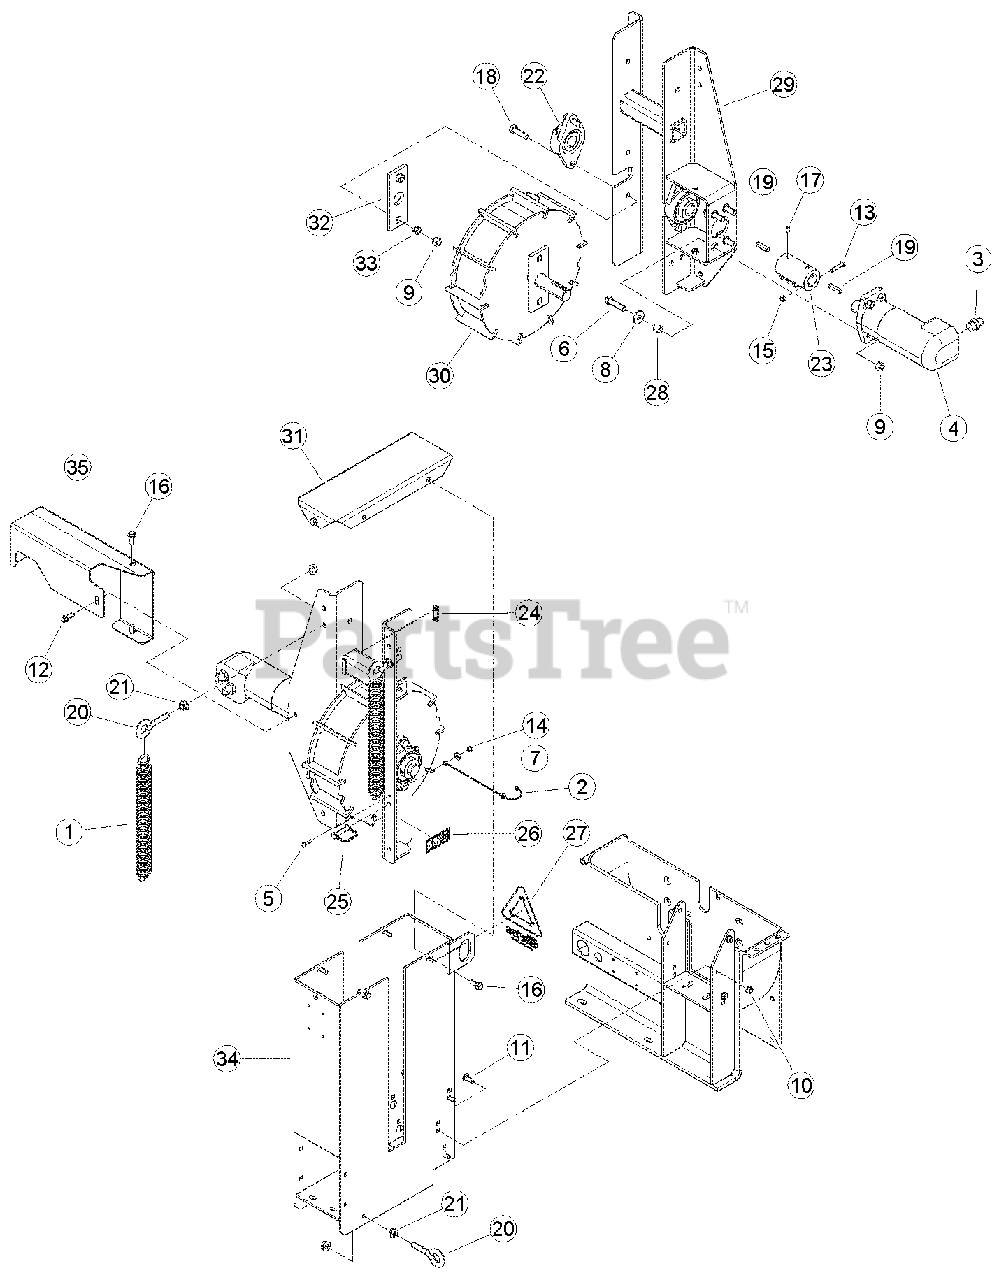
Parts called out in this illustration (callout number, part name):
1	SPRING, EXTENSION
2	LANYARD, NYLON
3	ADAPTER, -10 MORING / -8 MJIC
4	MOTOR, 19 CU IN HYDRAULIC
5	BOLT, 1/4 X 1 HEX HD GR5 ZP
6	BOLT, 1/2 X 2 HEX HD GR5 ZP
7	WASHER, 1/4 FLAT ZP
8	WASHER, 1/2 FLAT ZP
9	NUT, 1/2 CENTERLOCK GRB ZP
10	NUT, 3/8 SERR FLANGE NC ZP
11	BOLT, 3/8 X 1 CRG GR5 NC ZP
12	SCREW, 3/8-16 X 1 LG THD CUTT ZP
13	BOLT, 5/16 X 1-1/2 HEX HD GR5 ZP
14	NUT, 1/4 NE NYLOCK ZP
15	NUT, 5/16 NE NYLOCK ZP
16	BOLT, 3/8 X 1 SERR FLANGE GR5 NC ZP
17	SET SCREW, 3/8 X 1/2 CUP PT SKT
18	BOLT, 1/2 X 1-3/4 HEX HD GR5 NC ZP
19	KEY, 5/16 SQUARE X 1-1/2 LONG
20	EYEBOLT, 1/2 X 2 ZP
21	NUT, 1/2 SERR FLANGE NC ZP
22	BEARING, 1-1/4" DIA 2 BOLT FLANGE
23	COUPLER, 1-1/4" SHAFT
24	WEAR PAD, STD.SPRING HD FRONT
25	PIN, SNAP 3/8 X 1-1/2 USABLE LGH
26	DECAL, CRUSHING ISO
27	DECAL, CHIP IT
28	SPACER,0.75 X 0.620
29	WELDMENT, ROLLER SLIDE
30	WELDMENT, TOP GRAB ROLLER
31	WELDMENT, TOP ROLLER COVER
32	BEARING, SLIDE
33	SPACER, .75 OD X .5 ID X .37
34	WELDMENT, ROLLER SUPPORT 5 IN
35	WELDMENT, HYD. MOTOR COVER
